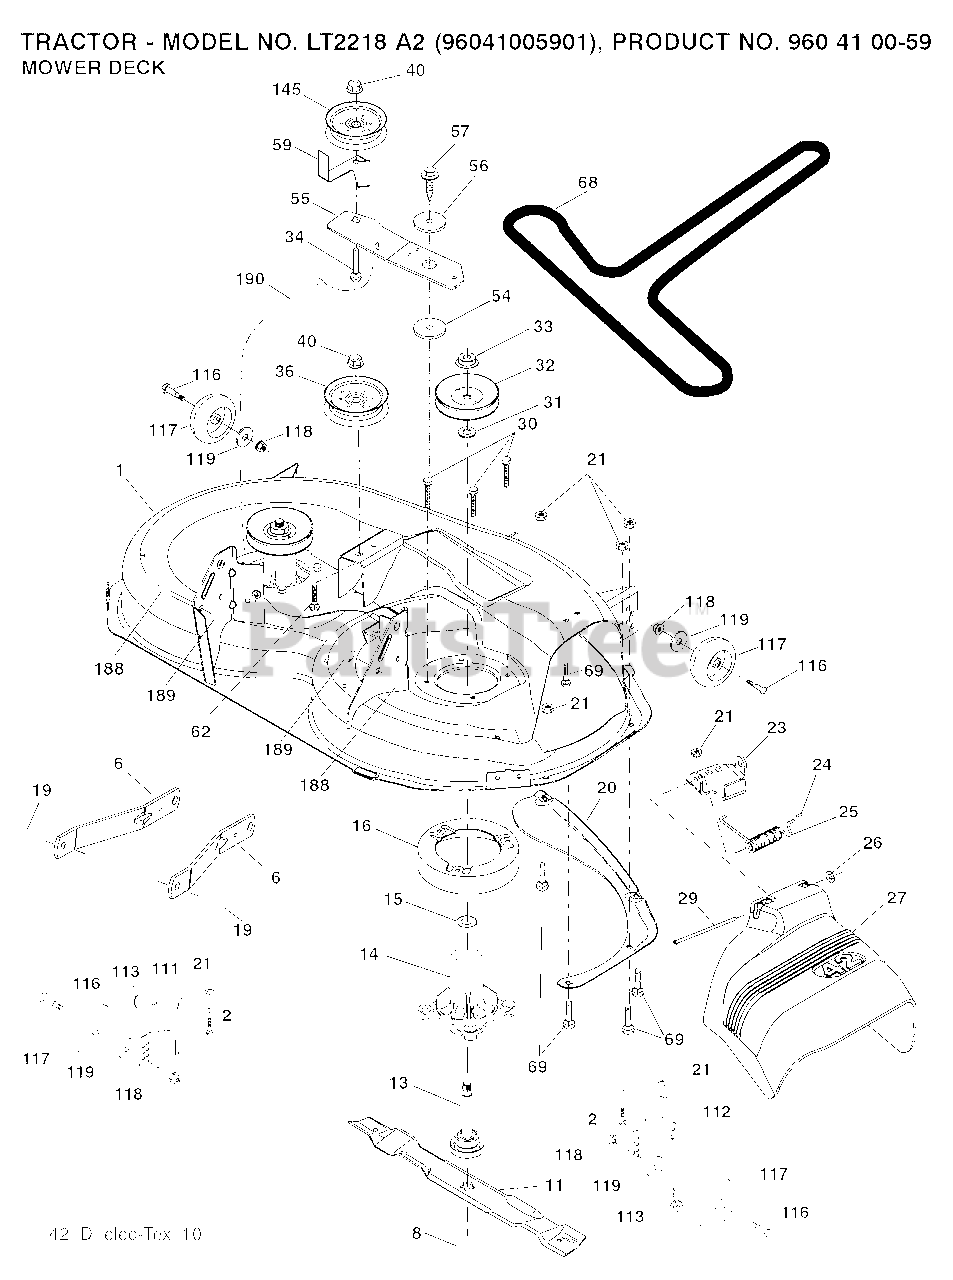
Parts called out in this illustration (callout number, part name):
1	DECK.WELDMENT.42"
2	BOLT
6	ARM.SUSPENSION.MOWER.R
8	BOLT.WASHER.ASM.7/16-2
11	42" HI-LIFT BLADE
13	SHAFT.ASM.MDRL.N/GREASE.38
14	HOUSING MANDREL
16	STRIPPER, MWR ROUND
19	BOLT.SHOULDER
20	BAFFLE.VORTEX
21	LOCKNUT
23	BRKT.DEFLECTOR.38"2005+
24	CAP-SLEEVE LT
25	SPRING.TORSION.DEFLECT
26	NUT PUSH M
27	SHIELD.DEFLECTOR.MOWER.42"BLAC
29	ROD.HINGE
30	SCREW, WASHER HEAD
31	WASHER.SPACER.MANDREL
32	PULLEY/MANDREL
33	NUT.FLANGE.LOCK.TOP
34	BOLT.3/8-16X1.50
36	PULLEY.IDLER.2006
40	NUT LOCK FLG 3/8-16 UNC
55	IDLER.ARM
56	SPACER.RETAINER
57	SCREW 3/8-16X1
59	GUARD, BELT
62	BOLT
68	BELT V SECONDARY
69	BOLT
111	BRKT.WHEEL.GAUGE.LH.42"
112	BRKT.WHEEL.GAUGE.RH.42"
113	BOLT.5/16HEX.WHS.HD
117	WHEEL.GAGE.HALF.SPOKED
118	LOCKNUT
119	WASHER
145	PULLEY.IDLER.48"PRIMARY
188	STUD.FASTNER.W/ANTI-ROTATE
189	NUT LOCK HEX FLANGE 5/16-18
190	SPRING.MOWER.DRIVE.ELECTRIC
